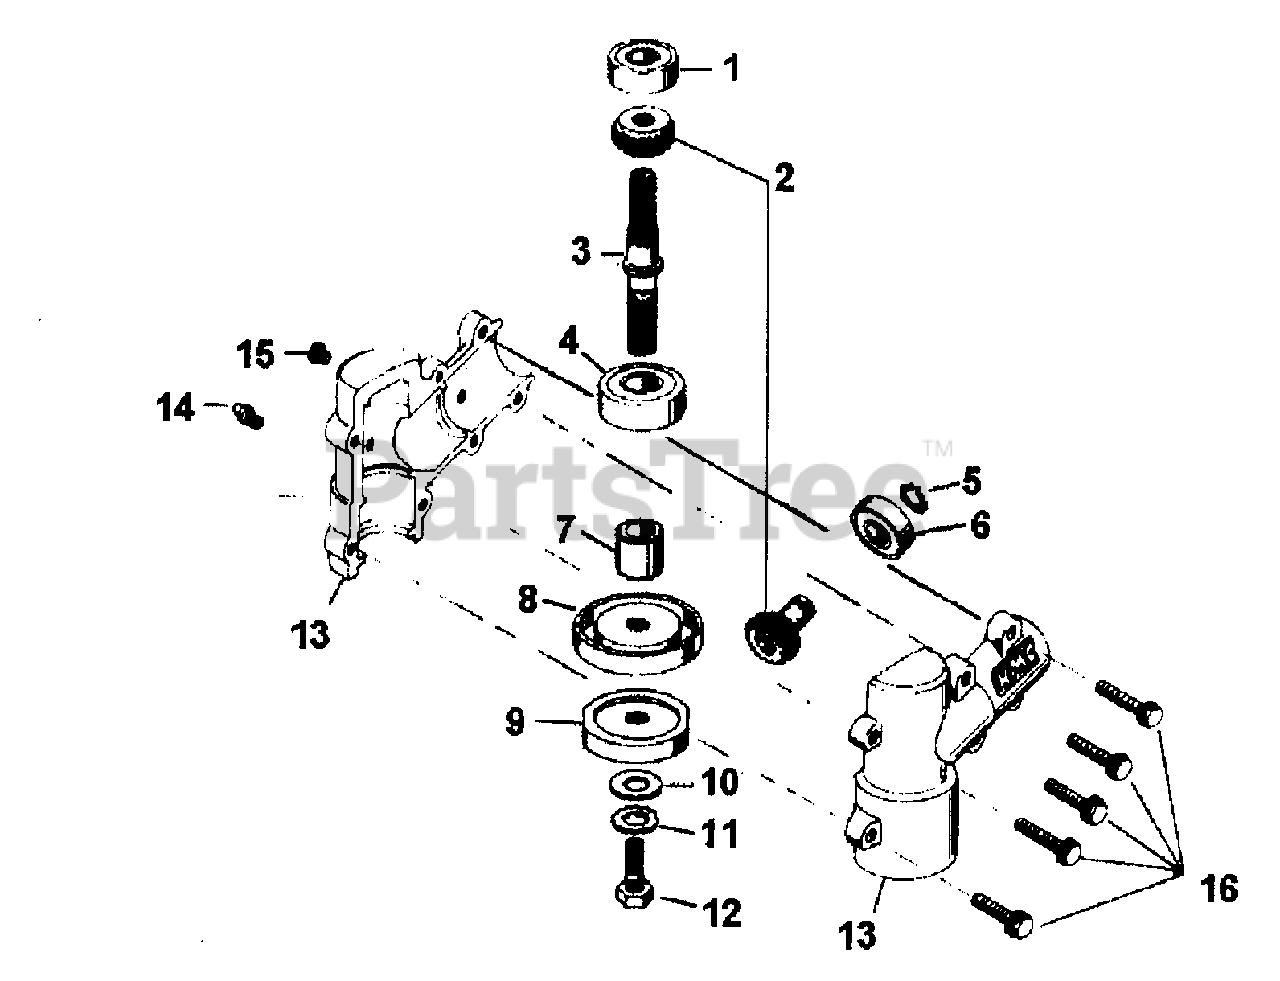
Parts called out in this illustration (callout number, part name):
1	BEARING
3	SHAFT, GEAR
5	RING
6	BEARING
9	HOLDER B
10	WASHER, FLAT
11	WASHER, LOCK
12	BOLT
13	HOUSING SET
14	FITTING, ZERK
15	SCREW, SELF TAPPING
16	SCREW, SELF TAPPING
